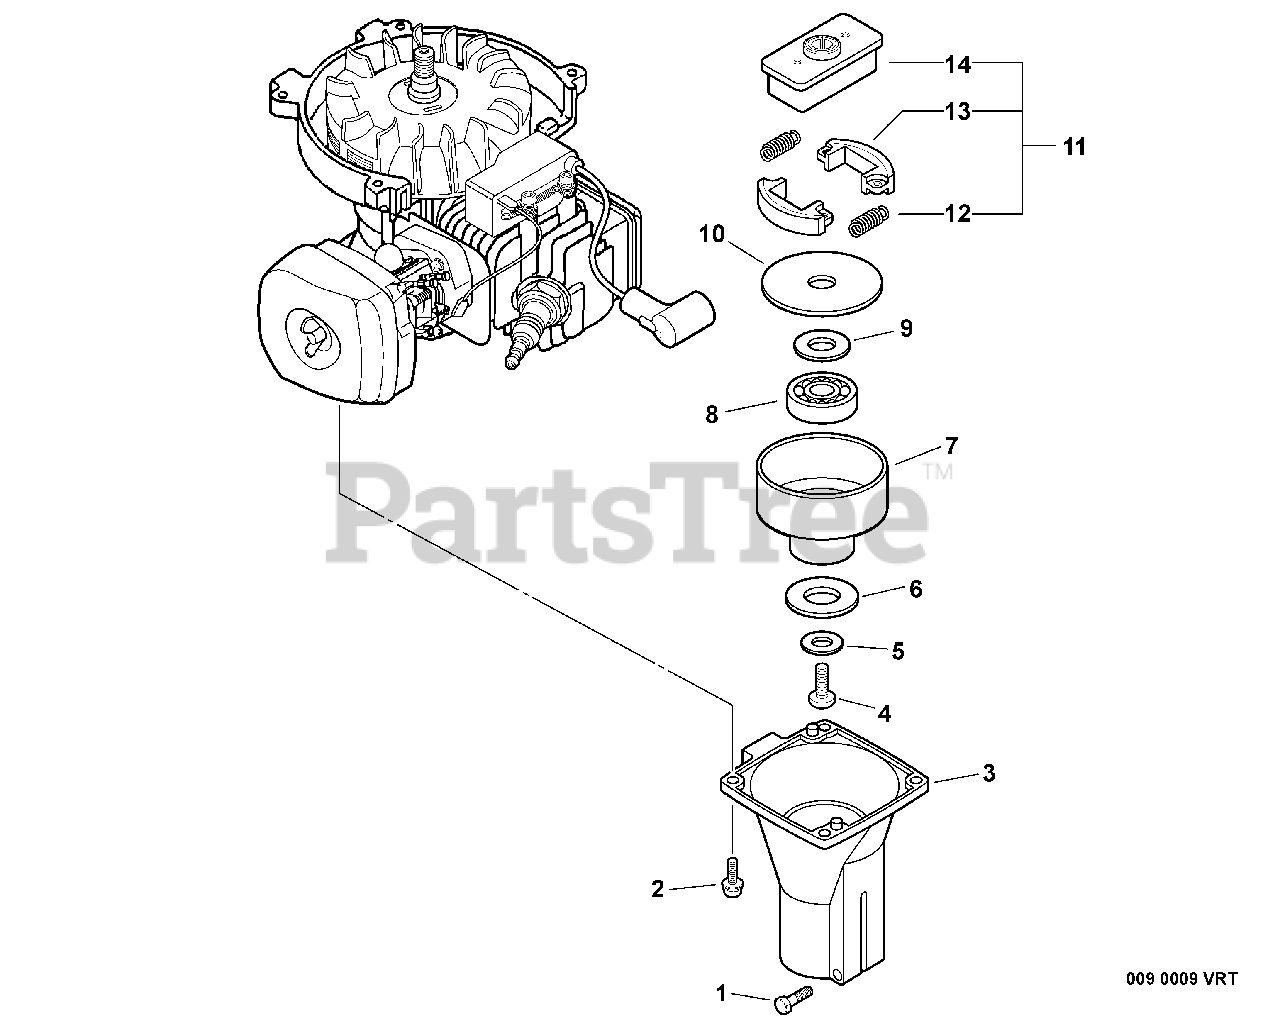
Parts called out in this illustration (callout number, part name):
1	BOLT - 5X25
2	SCREW - 4X14
3	CASE, CLUTCH
4	SCREW - 6X12
5	WASHER, CLUTCH
6	WASHER, CLUTCH
7	DRUM, CLUTCH
8	BEARING, BALL - 6000
9	WASHER - 10
10	PLATE, CLUTCH
11	CLUTCH ASSY
12	SPRING, CLUTCH
13	SHOE, CLUTCH
14	HUB, CLUTCH
